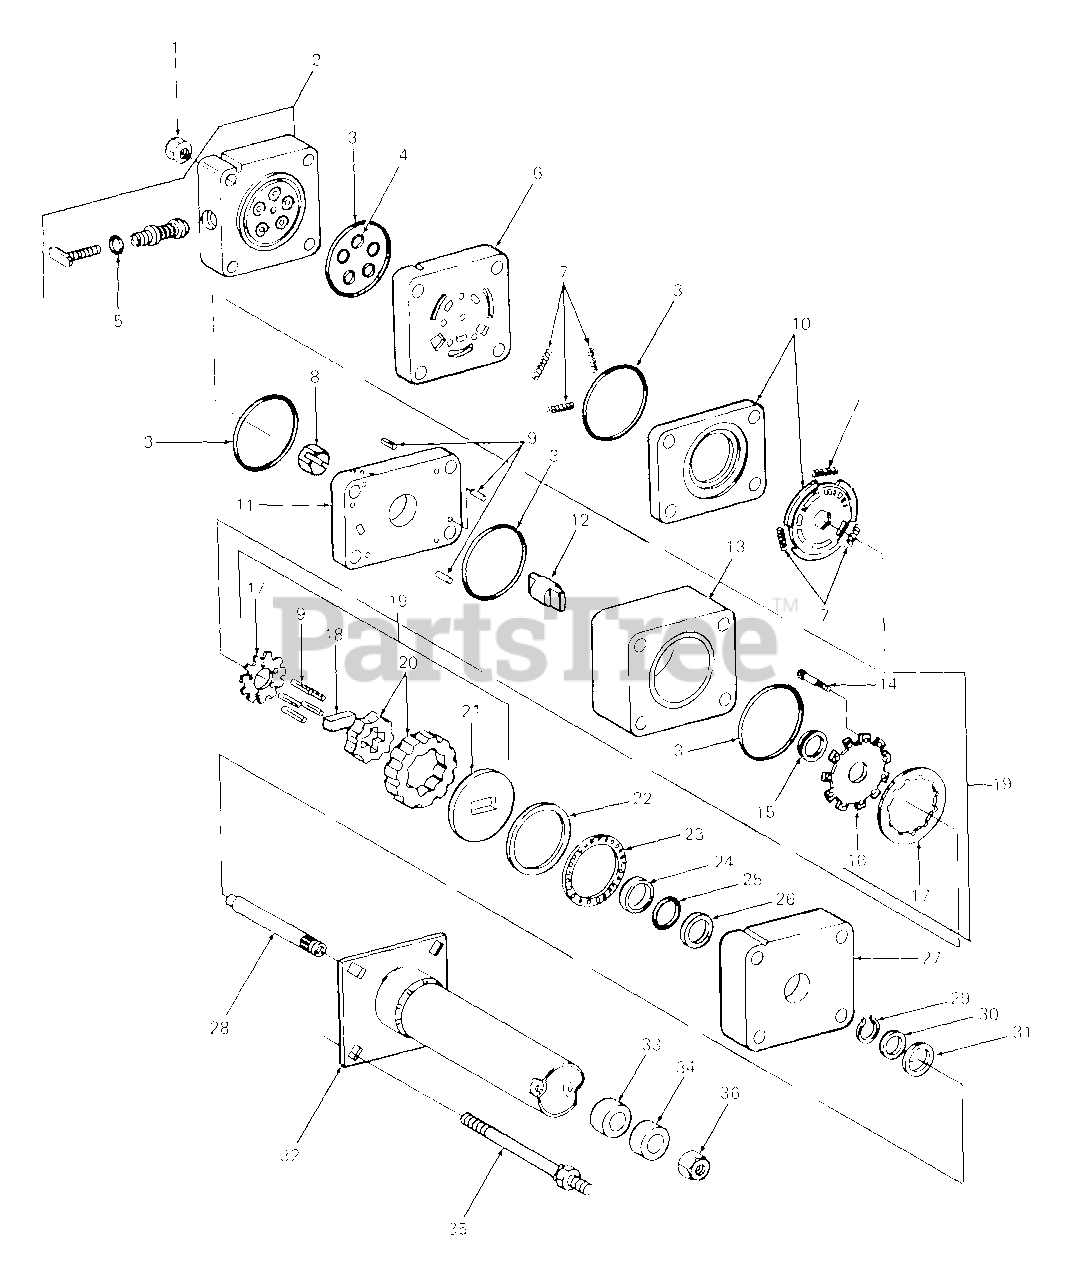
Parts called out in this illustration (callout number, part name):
1	Nut, Hex, 5/16-24
2	Power Cover & Check Valve Assy
3	Ring, Seal
6	Manifold, Port
8	Drive Assy, Hex
9	Roller Kit, Needle
10	Valve & Ring Assy
11	Manifold, Isolation
13	Ring, Metering
16	Cover, Commutator
17	Commutator & Ring Assy
18	Spacer, Drive Link
19	Metering Assy
23	Bearing, Thrust
24	Seal, Face
25	Ring, Back-up
26	Seal, Spacer
27	Plate, Upper Cover
28	Input Shaft Assy
29	Ring, Retaining
31	Plate, Retaining
32	Upper Cover & Tube Assy
33	Bearing, Column
34	Dust Seal, Column
35	Bolt, Special
36	Hex Jam Nut, 5/8-18
